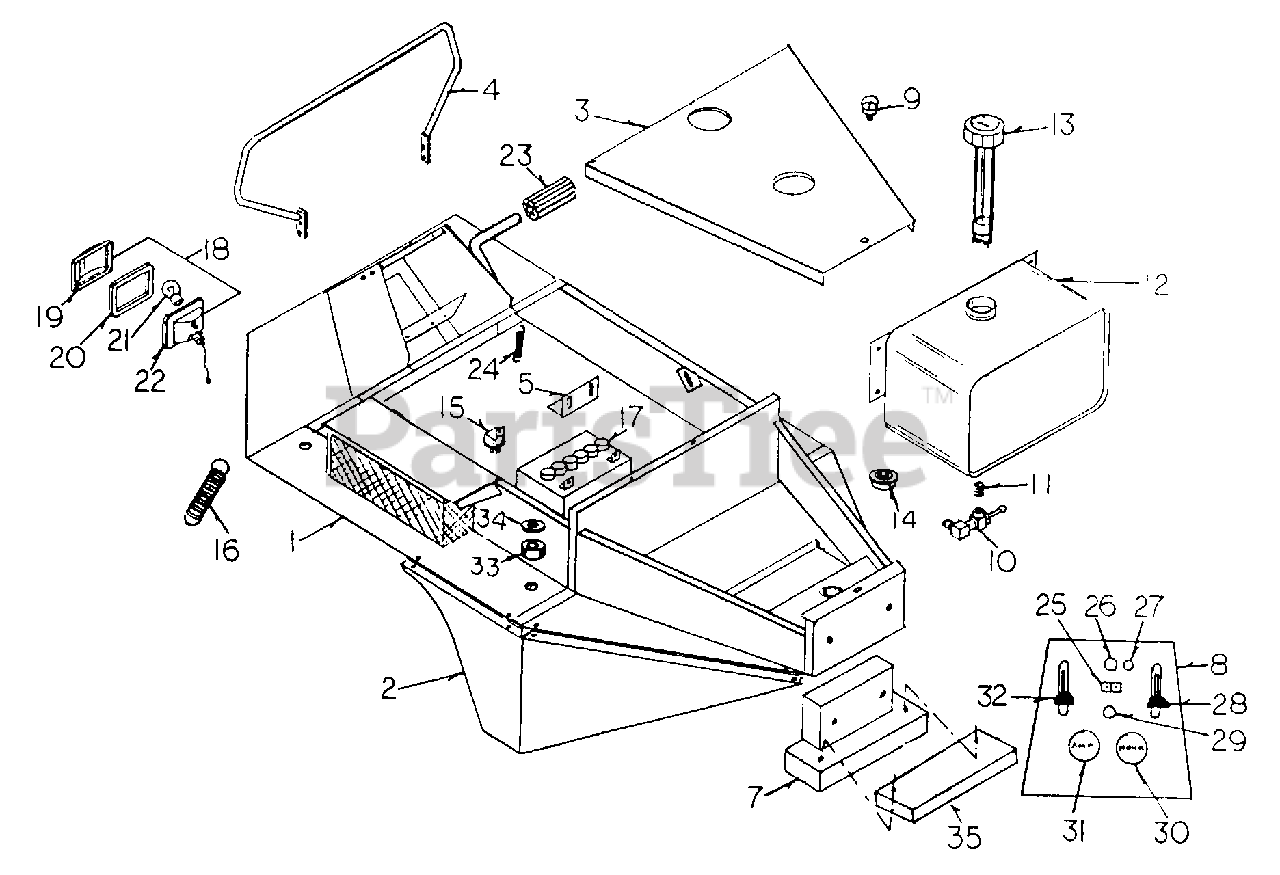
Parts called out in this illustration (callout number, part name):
2	FENDER - L.H.
13	FUEL TANK CAP w/Gauge
15	RELAY
17	BATTERY
18	LIGHT ASSEMBLY
19	LENS
20	GASKET
21	BULB
23	BRAKE PEDAL PAD
26	CLUTCH SWITCH
28	THROTTLE CABLE
29	IGNITION SWITCH
33	RUBBER BODY MOUNT
34	BODY MOUNT WASHER
35	TAIL WEIGHT - 13 lb.
